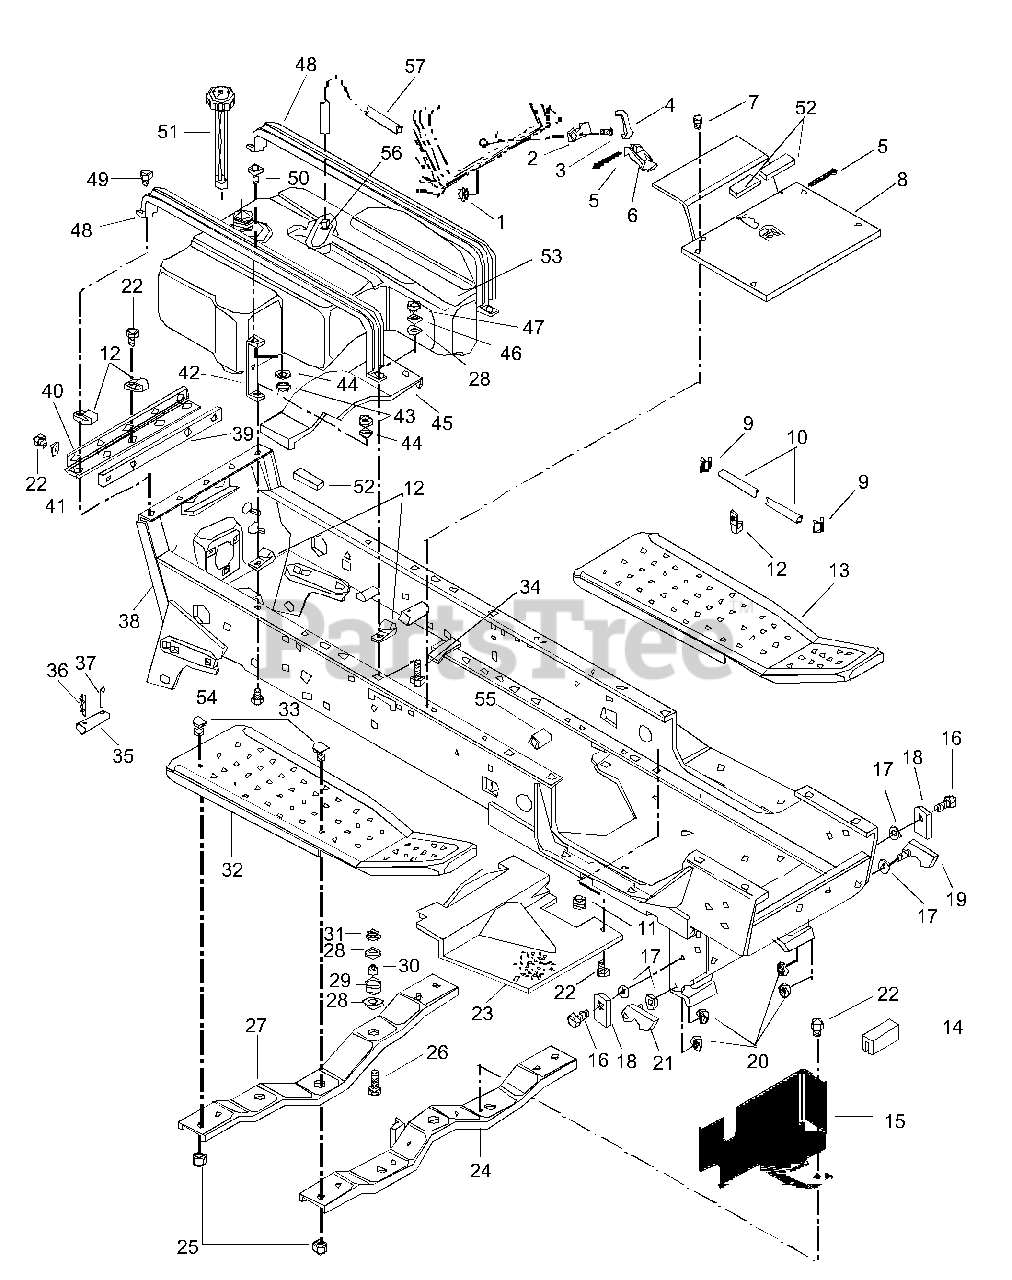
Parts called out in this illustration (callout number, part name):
1	Nut-Locking Dual Face 10-24
3	Screw-Machine 10-24 x .50
4	Spring-Deck Latch
5	Pin-Cotter .12 x 1.25
6	Lever-Deck Latch
7	Screw-Tapping .250-20 x .37
8	Plate-Floor
9	Hose Clamp
10	Fuel Line
11	Hole Plug 1.375
12	J-Clamp
13	Left Hand Running Board
16	Bolt-Hex .38-16 x 1.00 Grade 5
17	Spring Washer
18	Lock Stop
19	Latch Left Hand
20	Nut-Locking-Center .38-16
21	Latch Right Hand
22	Screw-Tapping .31 - 18 x .50
24	Front Channel
25	Nut-Flange-Locking .312 - 18
26	Bolt-Hex .31 - 18 x 1.25 Grade 5
27	Rear Channel
28	Washer-Flat-Steel .38 x .875 x .083
29	Grommet .125 x .438
30	Spacer .318 x .430 x .375
31	Nut-Locking-Center .31 - 18
32	Right Hand Running Board
33	Bolt-Round Head Square Neck .31-18 x .75
34	Bolt-Round Head Square Neck .31 - 18 x .75 Grade 2
35	Pin
36	Pin-Hair Internal .15 x .43 x 2.75
37	Pin-Cotter .12 x 1.0
38	Main Frame
39	Strap
40	Hinge
41	Washer-Flat-Steel .38 x .875 x .083
42	Support
43	Nut-Hex .250-20
44	Washer-Lock .250 x .077
45	Guard
46	Washer-Lock .312 x .097
47	Nut-Hex .31 - 18
48	Channel
49	Screw-Tapping .31 - 18 x .75
50	Screw-Socket Head .25-20 x .75
51	Gas Gauge & Cap
52	Foam Tape
53	Gas Tank Assembly
54	Bolt-Round Head Square Neck .25 - 20 x .75 Grade 5
55	Bushing-Sleeve .750 x .814 x 1.000
56	Fitting-Gas Tank
57	Gas Tank Fuel Line
